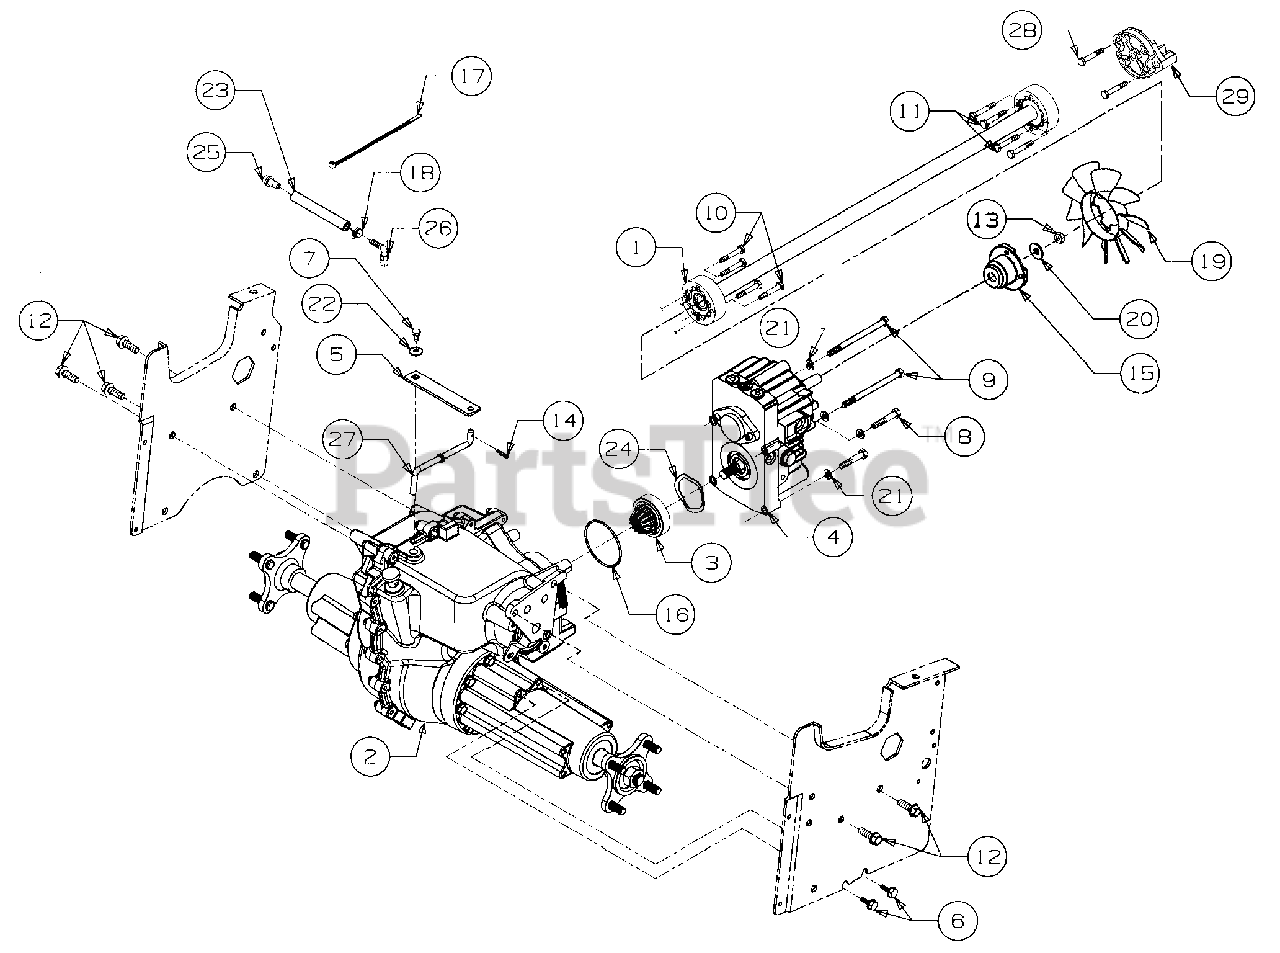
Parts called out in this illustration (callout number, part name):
1	Shaft Assembly, Drive, 27.87 Lg
2	Transmission Assembly, Hydro
3	Pinion Assembly, Input
4	Pump, Hydrostatic
5	Arm, Hydro Dump
6	Screw, Hex Wsh Tap, 5/16-18 x .75
7	Screw, Hex Wsh Tap, 1/4-20 x .75
8	Screw, Hex Cap, 5/16-18 x 1.75 GR5
9	Screw, Hex Cap, 5/16-18 x 4.5 GR5
10	Screw, Hex Patch, 1/4-20 x 1.25 GR5
11	Screw, Hex Patch, 1/4-20 x 1.62 GR5
12	Screw, Hex Wsh Tap, 3/8-16 x 1.25
13	Nut, Hex Center Lock Jam, 3/8-24
14	Pin, Internal Cotter, 5/16 Dia x 1.12
15	Adapter, Pump
16	O-Ring, 2.75 x .103
17	Tie, Self-Clinch Cable
18	Clamp, Hose
19	Fan, 10 Blade Cooling
20	Washer, Bell, .380 x .88 x .063
21	Washer, Lock, 5/16
22	Washer, Bell, .265 x .75 x .062
23	Line, Fuel, 7in (10ft Bulk)
24	Washer, Wave, 1.96 x 2.44 x .06
26	Fitting, Elbow
27	Rod, Hydro Disengagement
28	Screw, Hex Patch, M10-1.50x 90mm
29	Adapter, Drive Shaft
